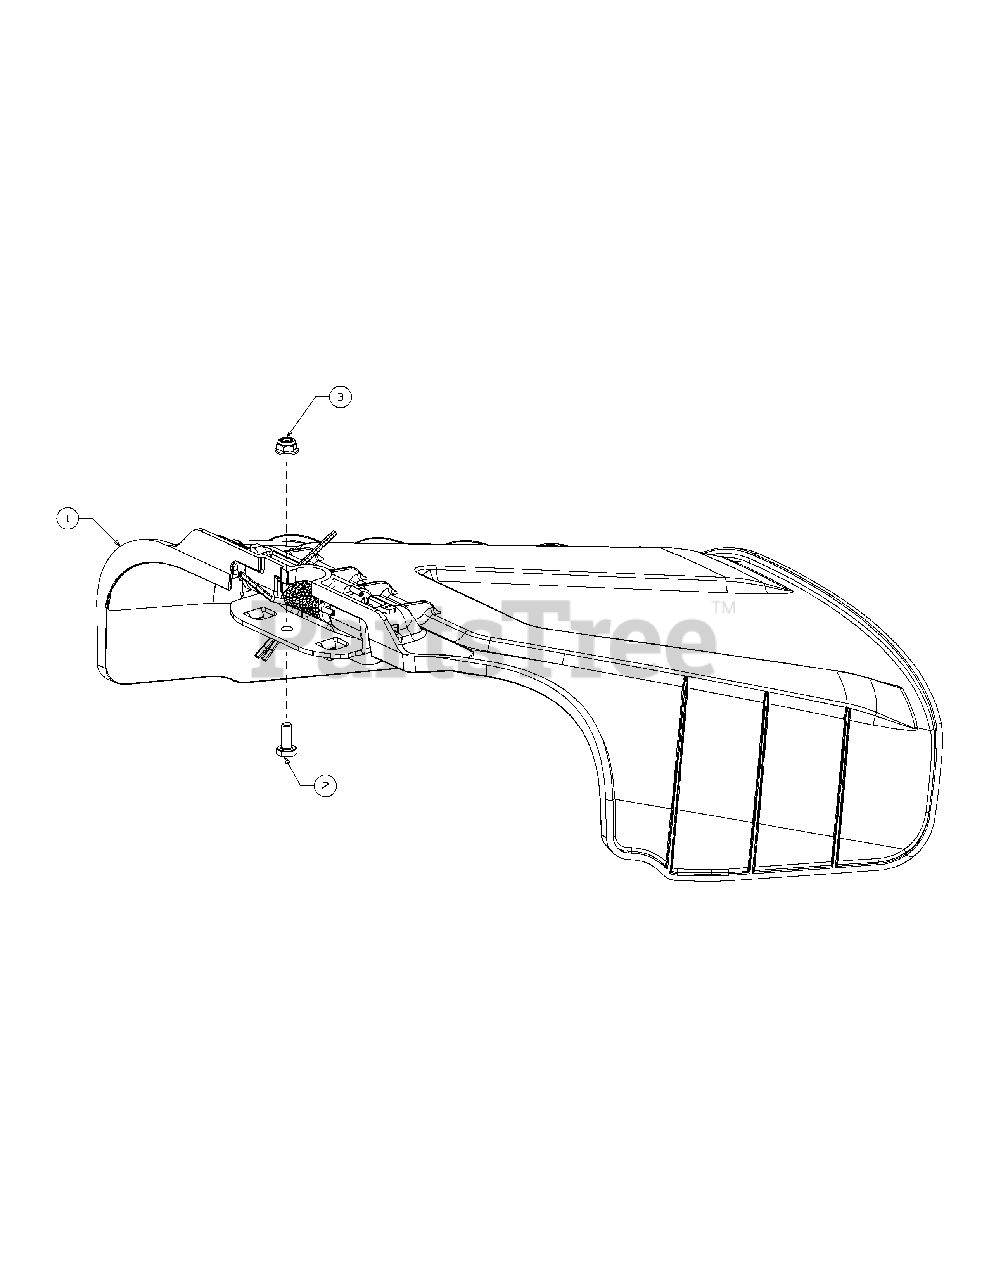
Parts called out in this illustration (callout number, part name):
1	Chute Deflector Assembly
1	Cap-Push
1	Spring-Torsion
1	Pin-Chute Hinge
2	Screw-1/4-20 X .62
